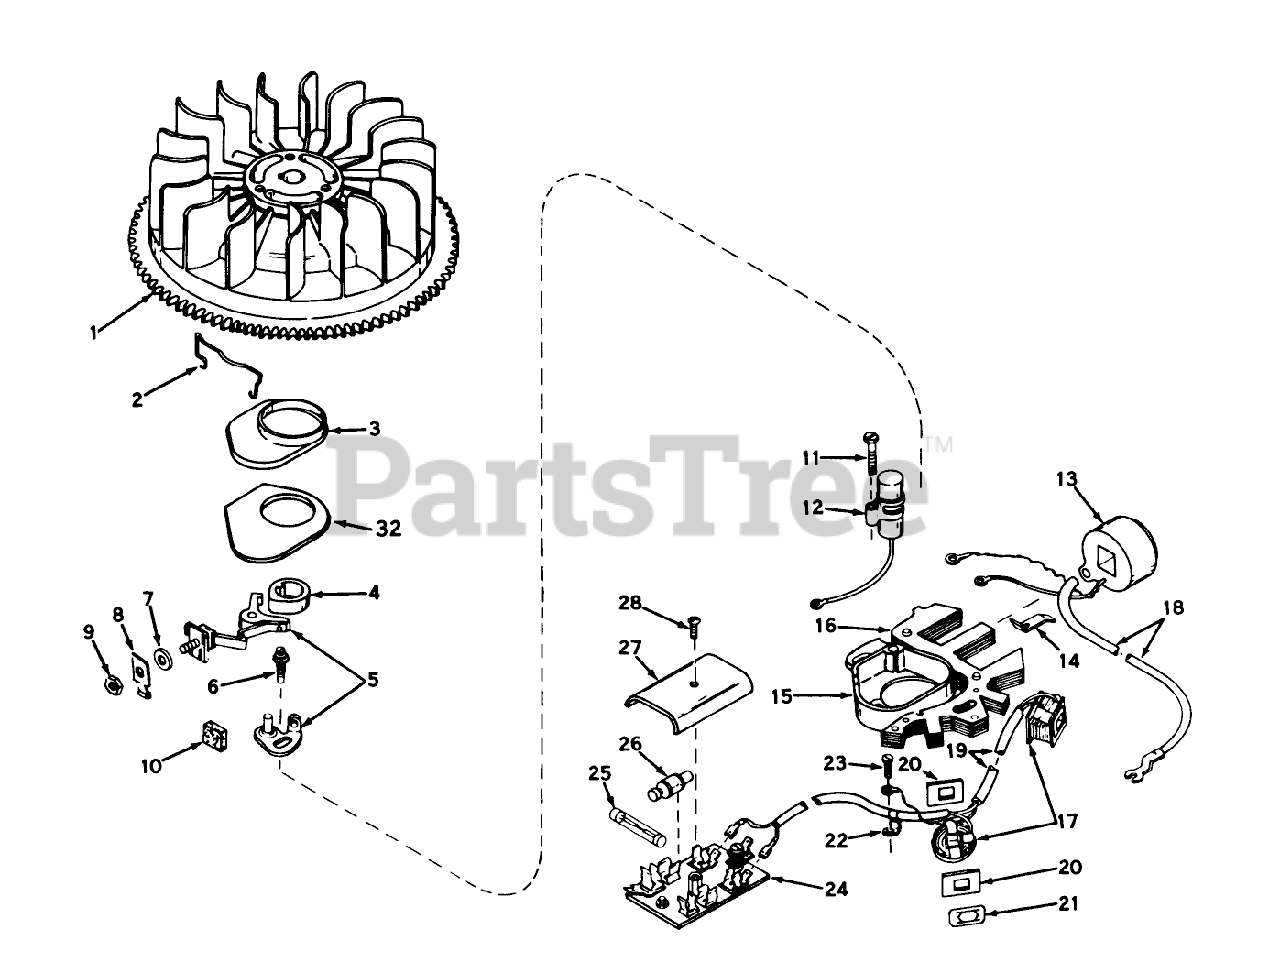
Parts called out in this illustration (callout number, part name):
1	Flywheel
2	Spring, Dust cover
3	Cover, Dust
4	Cam-Breaker
5	Breaker Assy.
6	Breaker Screw
7	Washer
8	Terminal
9	DECAL
10	Felt,Cam Wiper
11	Condenser Screw
12	Condenser
13	Coil Assy. (Incl. No. 12)
14	Spring Coil Wedge
15	Stator Plate Assy. (Incl. Nos. 2, 3, 5 Thru 28 32)
16	DECK ASM
17	Generator Coils Leads
18	Wire, Lead
19	Sleeve, Insulation
20	Shield, Coil
21	Clip, Coil fastening
22	Clip, Ground
23	Screw, Ground
24	Plate, Rectifier (Does not incl. 25 26)
25	Fuse
26	Rectifier
27	Cover, Panel
28	Screw
32	Gasket Dust
